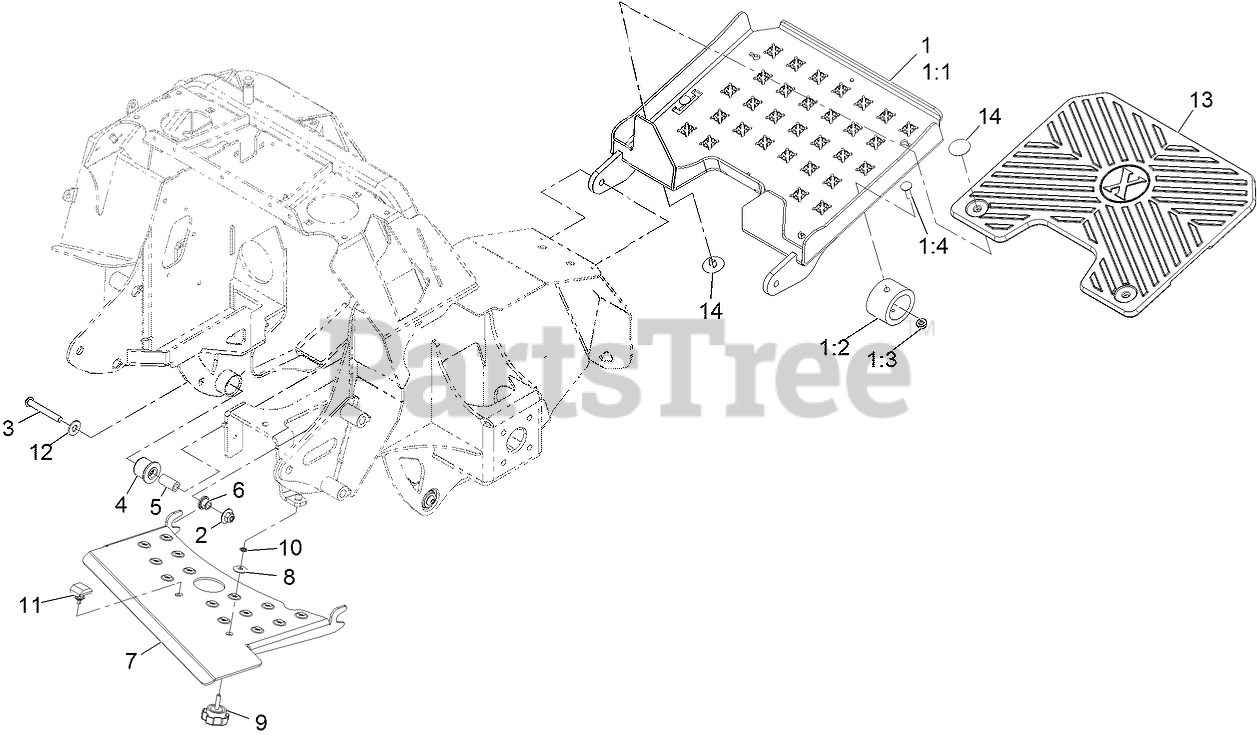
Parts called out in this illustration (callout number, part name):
1	ASM-Platform
1:1	Weld-Platform [blk-Txt]
1:2	BUMPER-ISOLATOR
1:3	NUT-HF, NI
1:4	BOLT-CARR
2	Nut-Nyloc 3/8-16 Flg
3	Screw-HSBH
4	BUSHING-RUBBER, SUSPENSION
6	BUSHING-FLANGED
7	BUSHING-FLANGED
8	WASHER-BELLEVILLE
10	NUT-RETAINING
11	BUMPER-ROPS
12	WASHER-FLAT
13	Pad-Platform
14	Rivet-Ratchet
